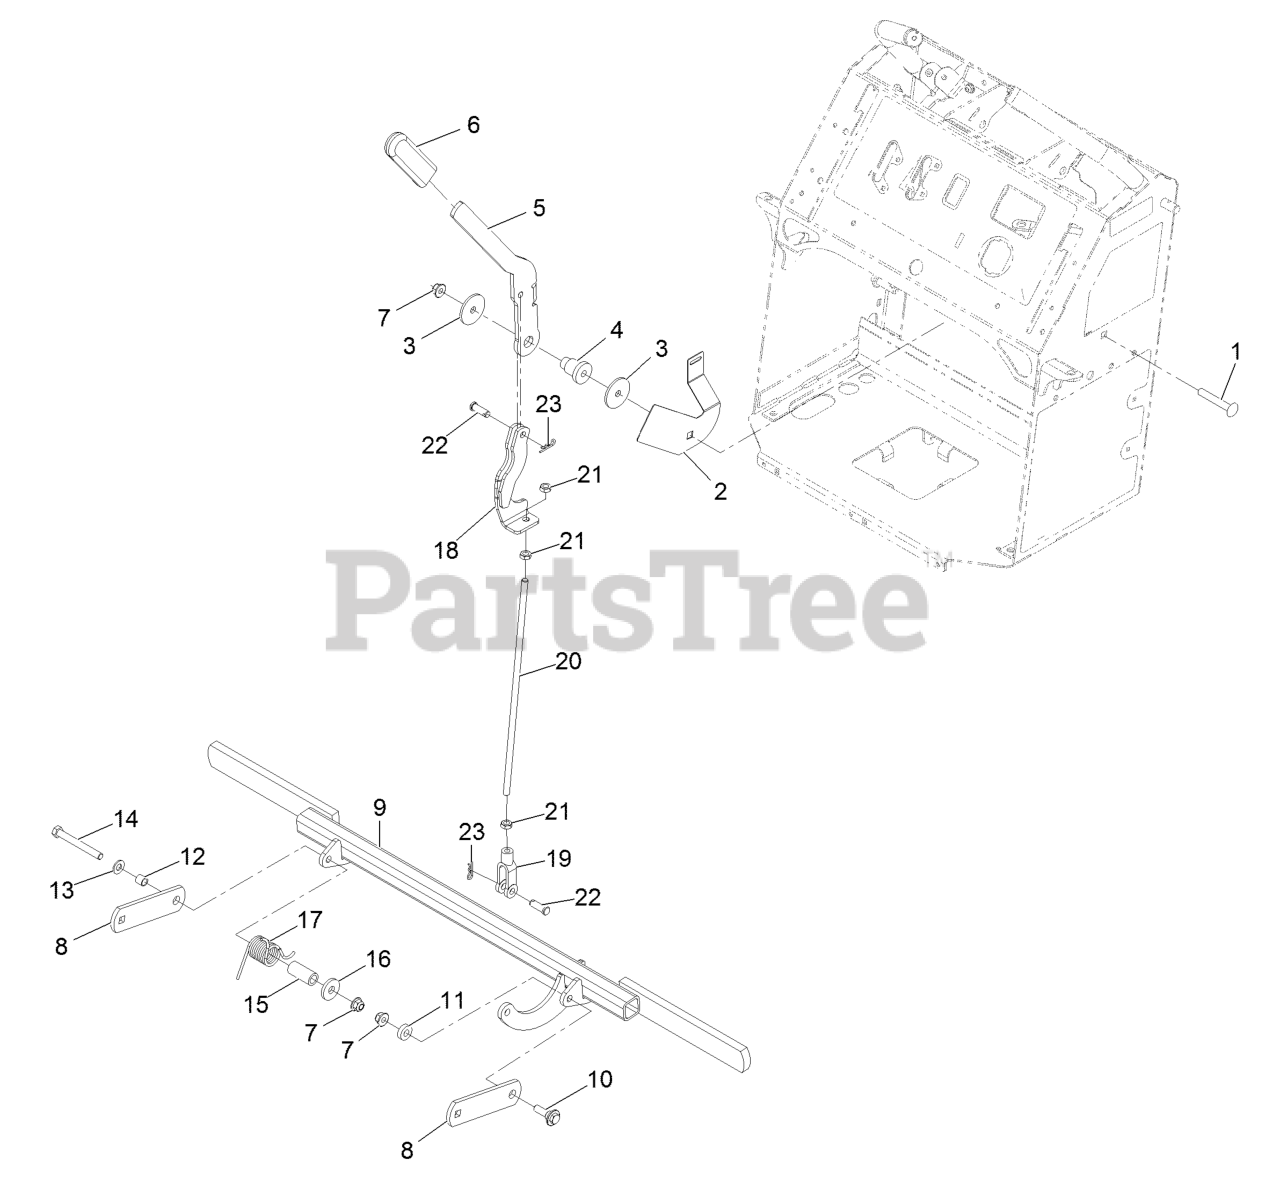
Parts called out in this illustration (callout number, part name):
1	Bolt-Carriage 3/8-16 X 2 1/2
2	Plate-Switch, Brake
3	Washer-Rebound
4	Mount-Pulley
5	Lever-Brake
6	Grip-Lever
7	Nut-Nyloc 3/8-16 Flg
8	Support-Brake
9	Bar-Brake
10	Screw-Shoulder 3/8-16 X 1.295
11	Spacer
13	Washer-3/8 SAE
14	Screw-HH 3/8-16 X 3-1/4
16	Spring-Torsion
18	Arm-Brake
19	Yoke-Linkage, Brake
20	Rod-Brake
21	Nut-Jam 3/8-24
22	Pin-Clevis 3/8 X 1 1/6
23	Pin-Cotter
